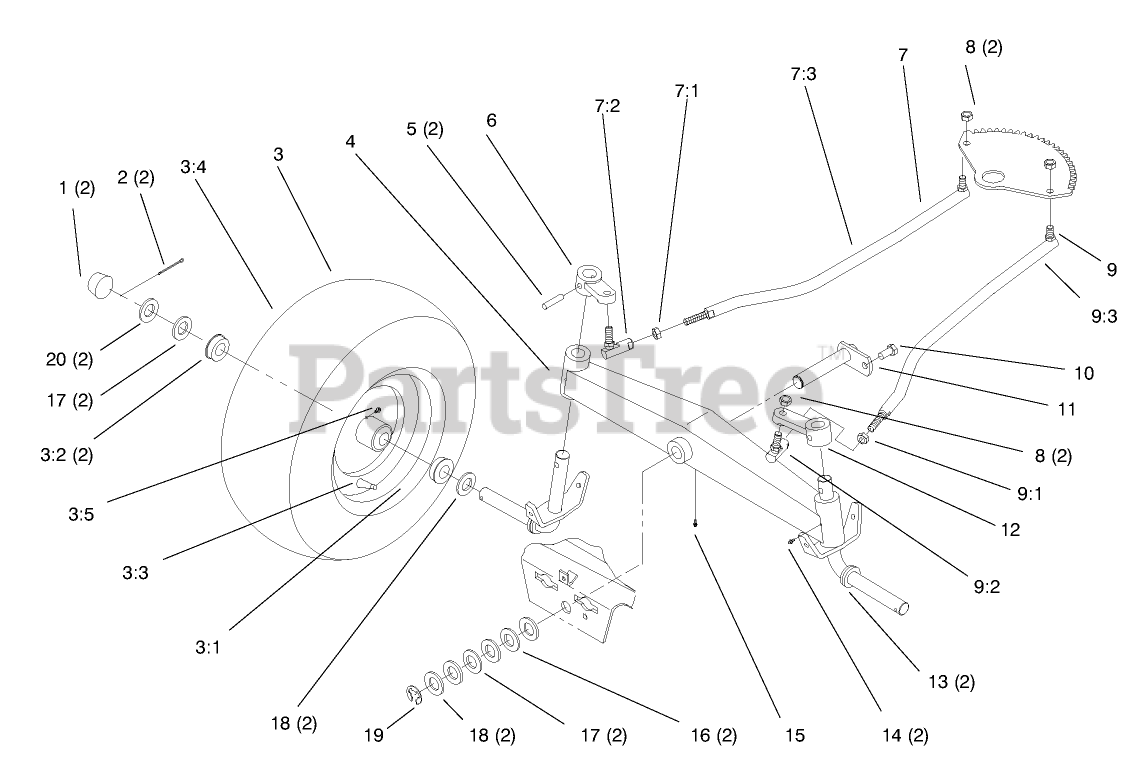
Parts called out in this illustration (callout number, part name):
1	CAP-HUB
2	PIN-COTTER
3:1	WHEEL ASM
3:2	BEARING-WHEEL
3:3	VALVE
3:4	TIRE (16 X 6.5-8) 2-PLY -2 WHEEL AXEL
3:5	ZERK-GREASE
4	AXLE ASM-FRONT
7	LINKAGE-STEERING, RH
7:1	Nut-Hex Jam
9	LINKAGE-STEERING, LH
9:1	Nut-Hex Jam
10	SCREW-HWH, TAPTITE
11	PIN-AXLE
14	FITTING-GREASE
15	FITTING-LUBE, 45 DEG
16	WASHER
17	WASHER
18	WASHER-SHIM
19	E-RING
20	WASHER-PLAIN
